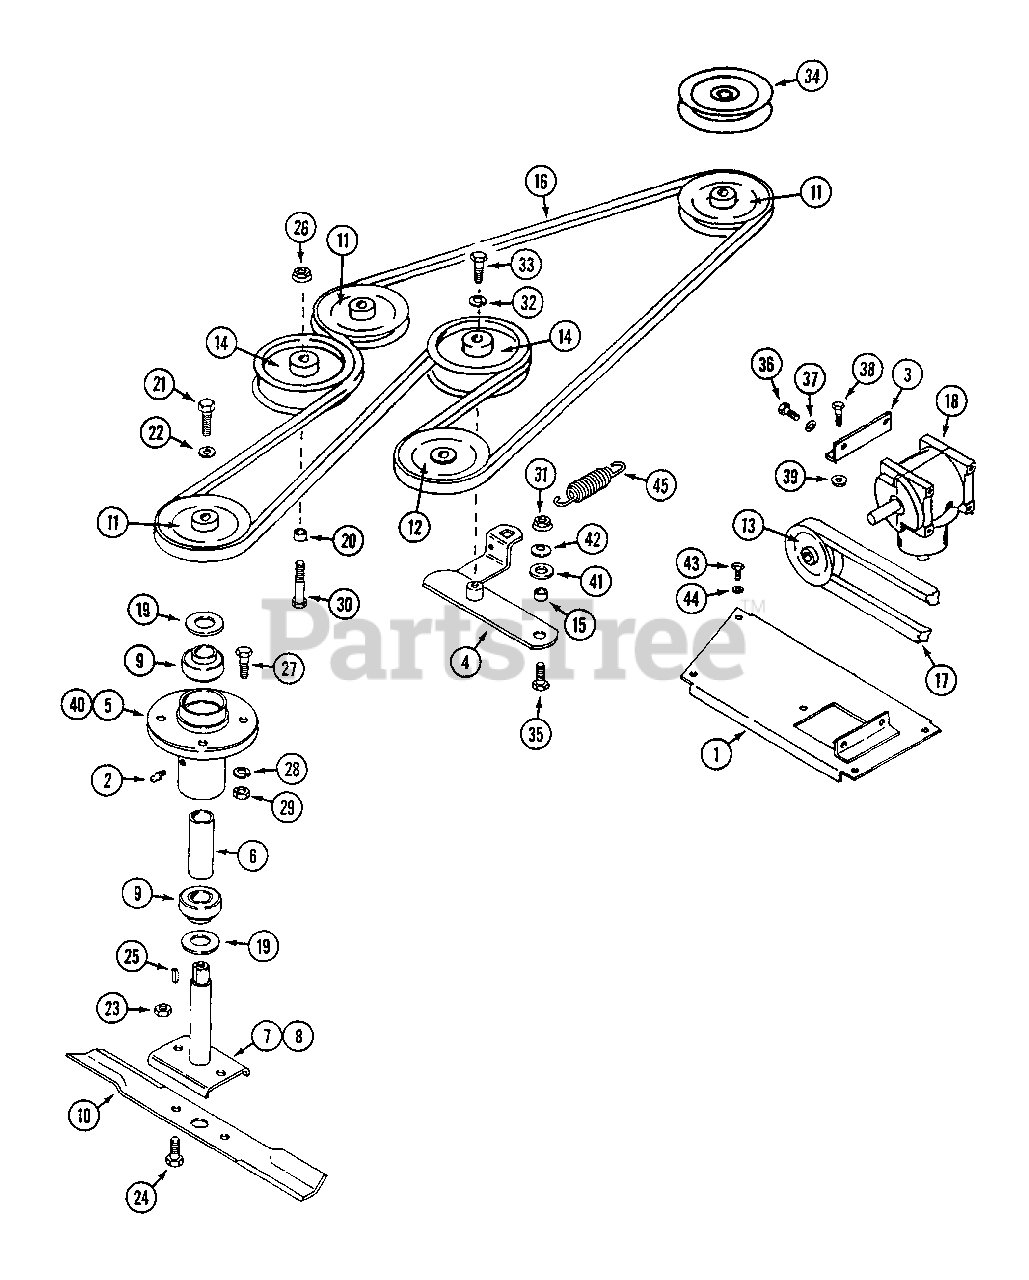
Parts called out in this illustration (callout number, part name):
1	MOUNT - gear box
2	FITTING - grease 1/4" - 28
3	ANGLE - gear box mount
5	HOUSING - spindle
6	SPACER - spindle
7	SHAFT - spindle, short
8	SHAFT - spindle, long
9	BEARING - spindle
10	BLADE - mower
11	PULLEY - spindle
12	PULLEY - gear box output
13	PULLEY - gear box input
14	PULLEY - idler
18	GEAR BOX - angle drive
19	SPACER - washer
21	BOLT - 3/8" - 24 x 1-1/4"
22	WASHER - 3/8" - 10 ga.
23	NUT - lock 3/8"
24	BOLT - 3/8" - 16 x 1"
25	KEY - 3/16" x 1"
26	NUT - 3/8" flange lock
27	BOLT - 7/16" - 14 x 1-1/4"
28	LOCKWASHER - 7/16"
29	NUT - 7/16" - 14
30	BOLT - 3/8" - 16 x 2-1/4"
31	NUT - 3/8" flange lock
32	LOCKWASHER - 3/8"
33	BOLT - 3/8" 16 x 1-1/4"
34	PULLEY - vac drive
35	BOLT - 3/8" - 16 x 1"
36	BOLT - 5/16" - 18 x 1"
37	LOCKWASHER - 5/16"
38	BOLT - 5/16" - 18 x 3/4"
39	NUT - 5/16" - 18 flange lock
40	HOUSING ASSEMBLY - spindle
41	WASHER - 5/8"
42	WASHER - spring
43	BOLT - 1/4" - 20 x 3/4"
44	LOCKWASHER - 1/4"
45	SPRING - tension
